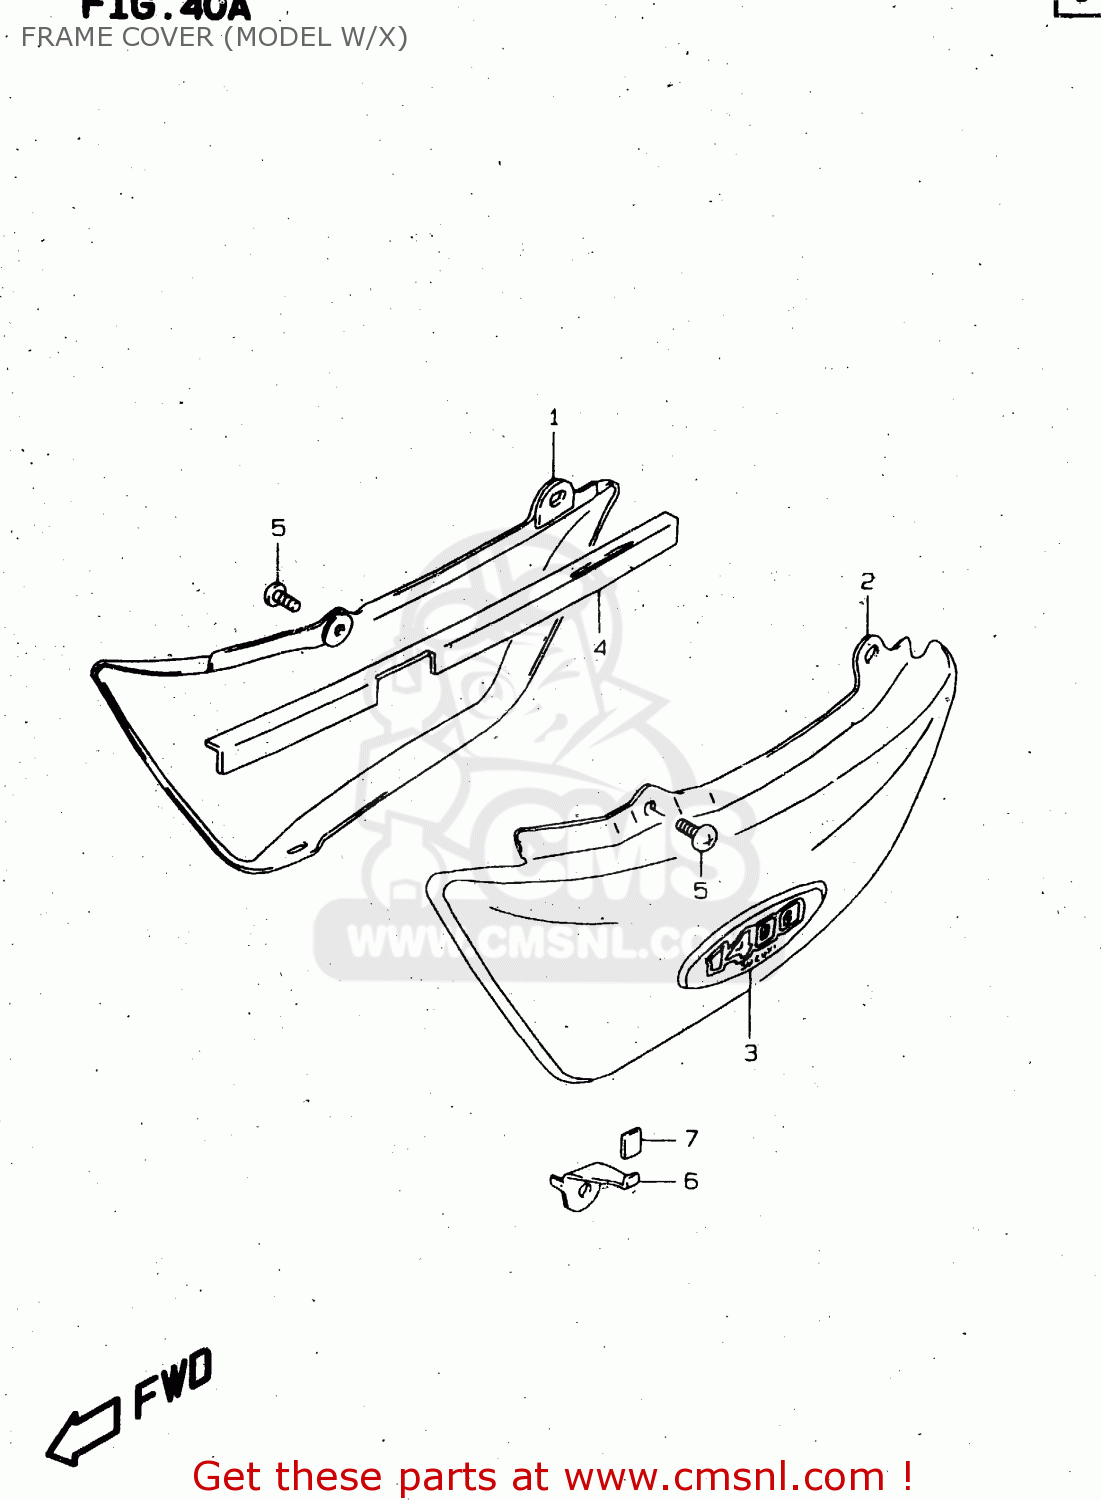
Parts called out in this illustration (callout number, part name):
1	1
2	COVER COMP,FRAME,LEFT
3	EMBLEM,FRAME COVER
4	PROTECTOR,FRAME COVER,R
5	SCREW 6X12
6	HOOK,FRAME COVER,L
7	CUSHION,FRAME COVER HOOK
